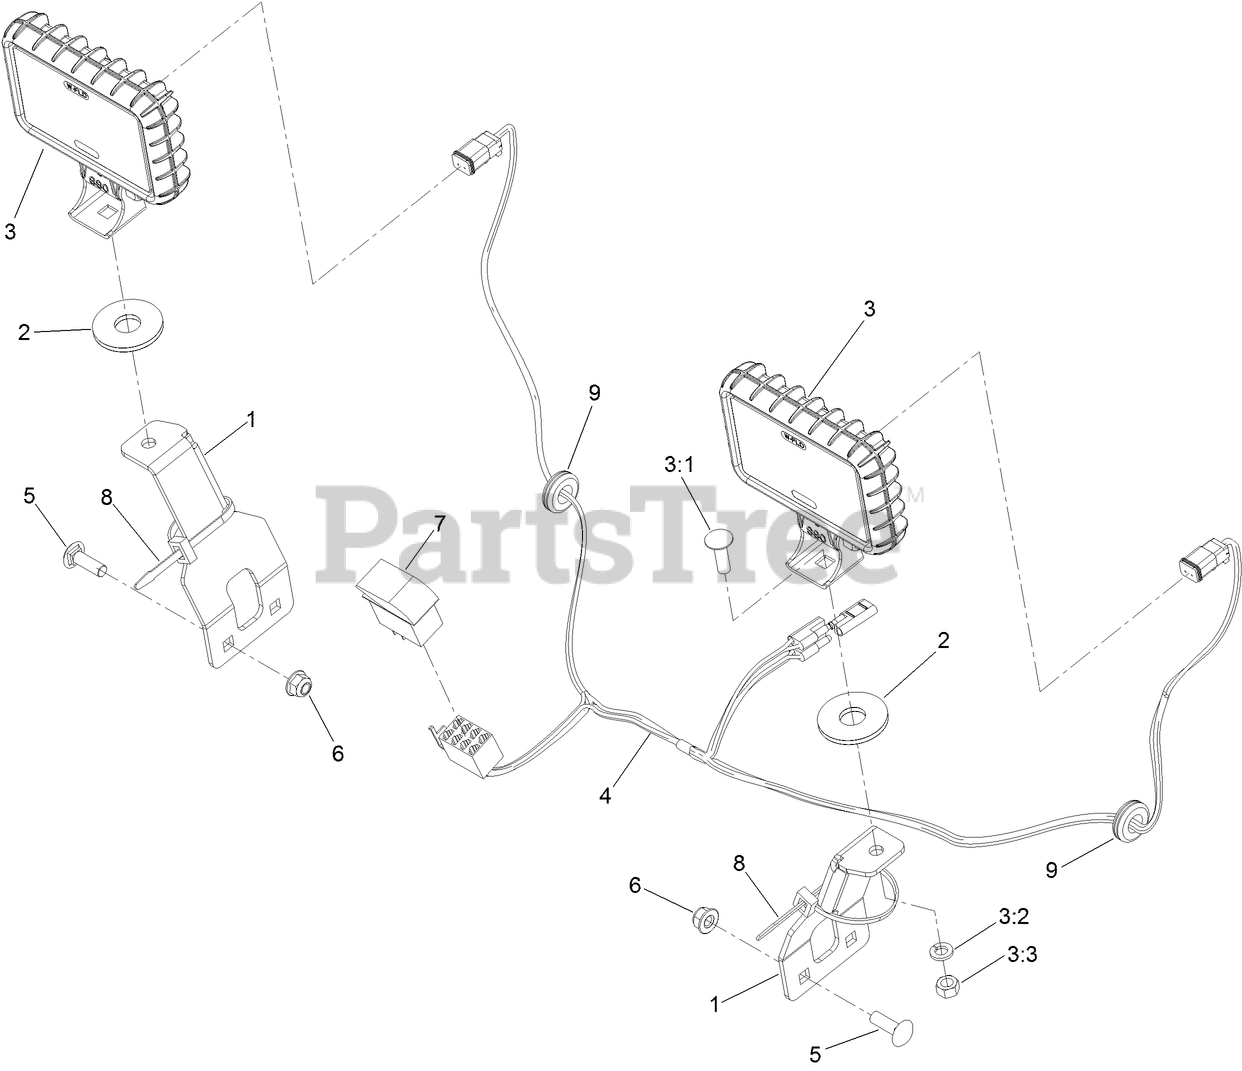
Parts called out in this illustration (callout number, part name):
1	BRACKET-MOUNT, LIGHT
2	WASHER-FRICTION, COMPOSITE
3	LIGHT-WORK, LED
3:1	SCREW-CARR
3:2	WASHER-LOCK
3:3	NUT-HEX
4	HARNESS-WIRE
5	SCREW-CARR
6	NUT-HF, NI
7	SWITCH-ROCKER
8	TIE-CABLE
9	GROMMET
